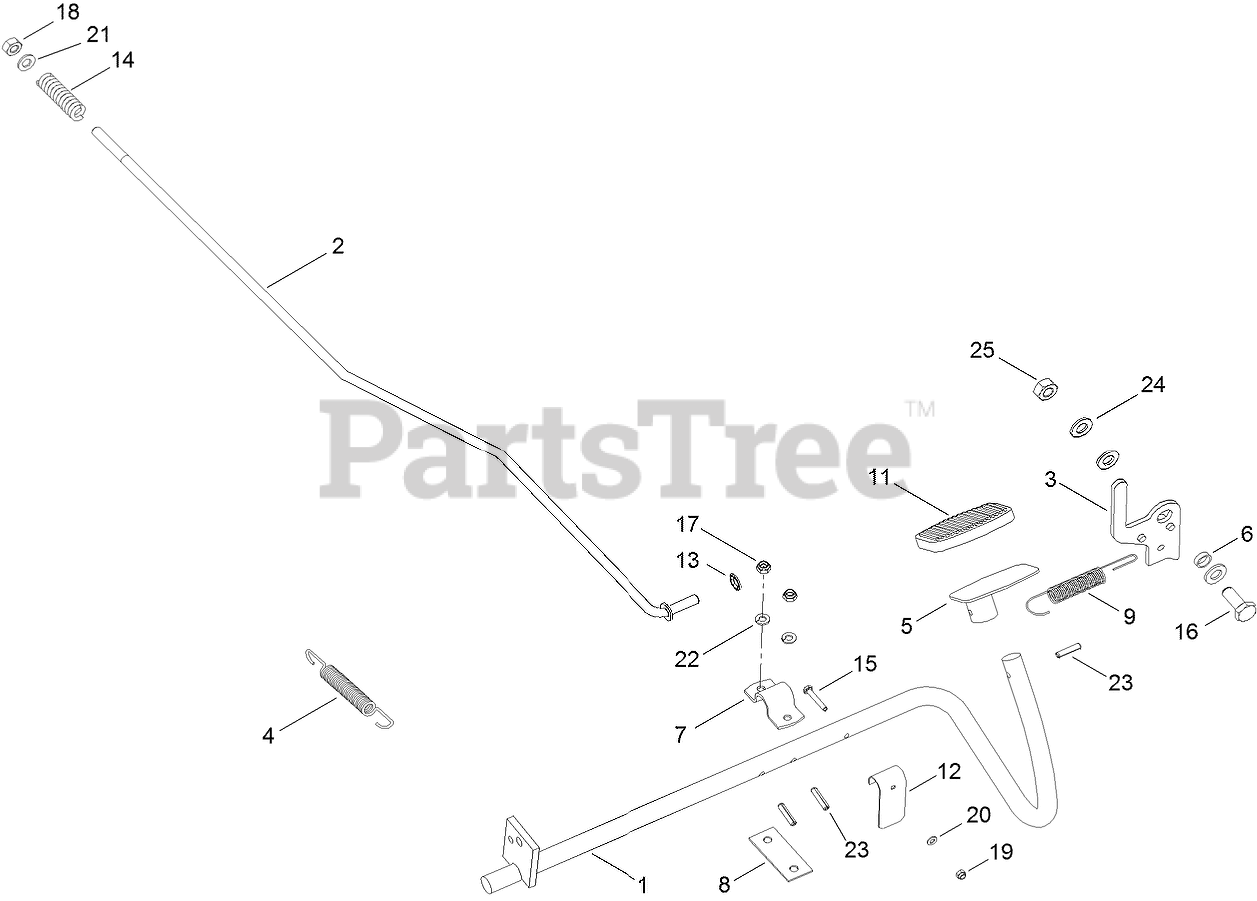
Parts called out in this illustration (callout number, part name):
2	ROD-BRAKE, LINKAGE
3	LEVER-PARKING BRAKE
4	SPRING
5	PEDAL-TRAVEL, BRAKE
6	SPACER
8	SPACER
9	SPRING-BRAKE, HAND
11	PAD-PEDAL
12	BRACKET-PARKING BRAKE
13	WASHER
14	SPRING-BRAKE
15	SCREW-HEX
16	SCREW-HEX
17	NUT-LOCK
18	NUT-LOCK, NI
19	NUT-HEX
20	Washer
21	WASHER-PLAIN
22	WASHER
23	PIN-SPRING
24	WASHER-FLAT
25	NUT-LOCK
